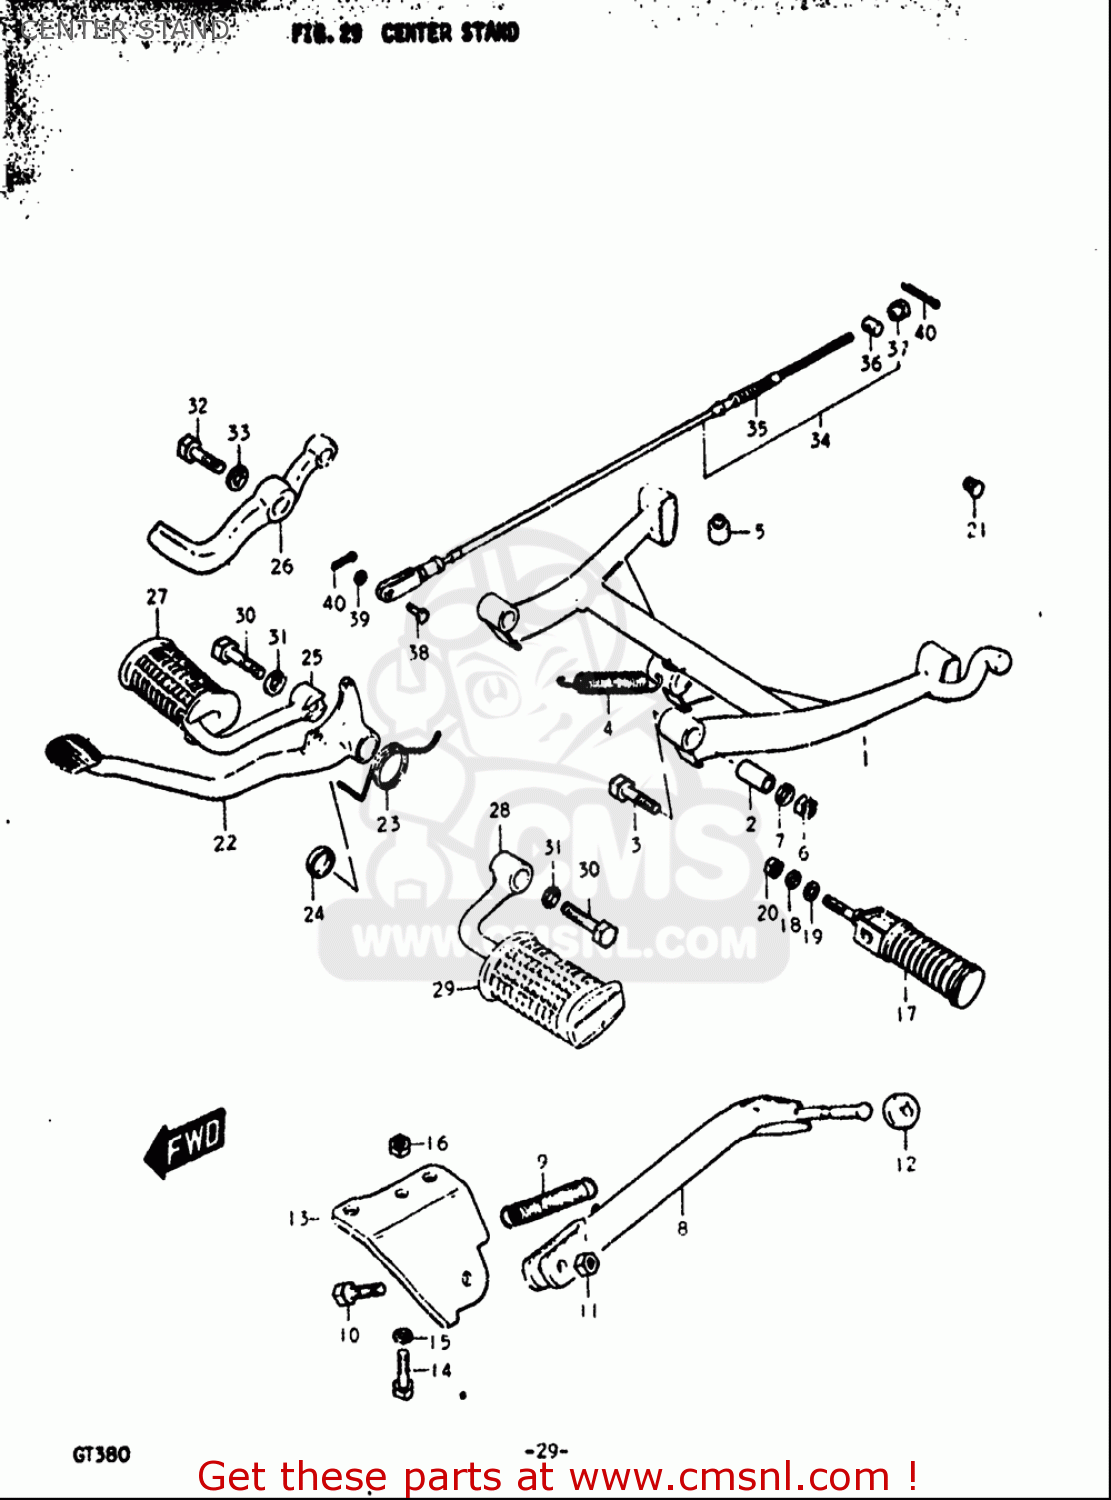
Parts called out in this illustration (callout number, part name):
2	SPACER(10.5X16X30)
3	BOLT(10X48)
4	SPRING
5	CUSHION
6	NUT
7	WASHER,LOCK
9	SPRING
10	BOLT(10X30)
11	NUT
12	CUSHION
14	BOLT(10X27)
15	WASHER,LOCK
16	NUT
17	FOOTREST ASSY,PILLION
18	WASHER,LOCK
19	WASHER
20	NUT
21	CAP(OD:14)
27	RUBBER,FOOTREST
30	BOLT
31	WASHER,LOCK
32	BOLT
33	WASHER,LOCK
34	CABLE ASSY,RR BRAKE
35	SEAL,DUST
36	PIN(13X18)
37	NUT
38	PIN(L:17.5)
39	WASHER
40	PIN
